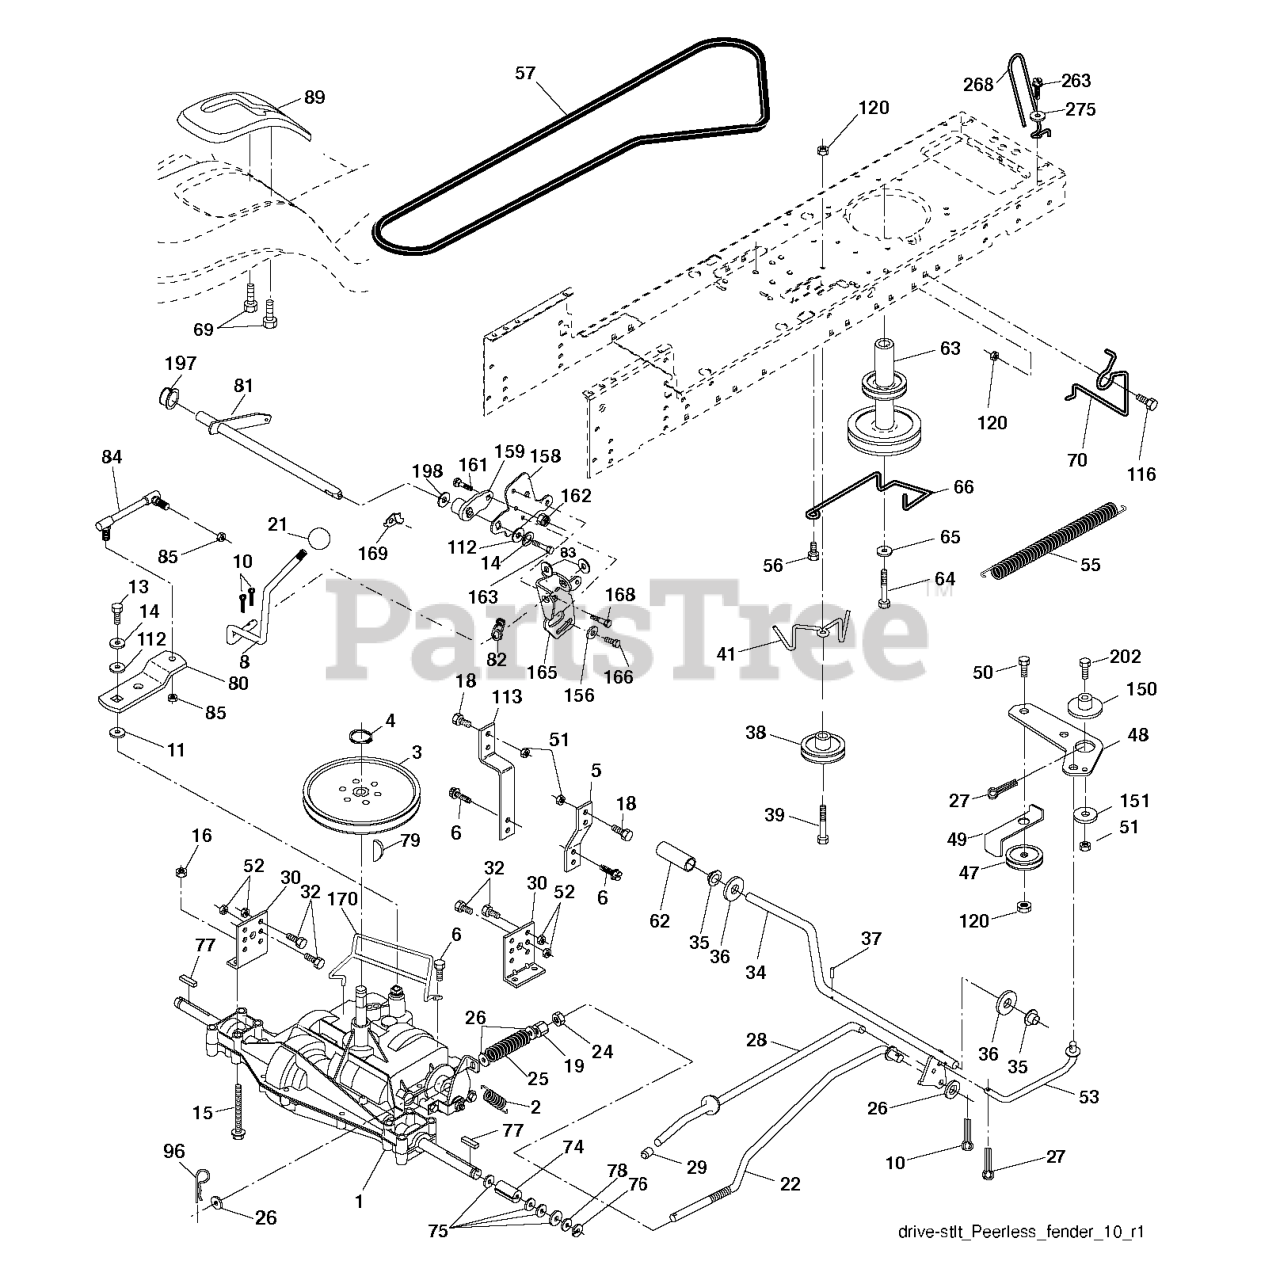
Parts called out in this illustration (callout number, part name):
2	SPRING,BRAKE RETURN
3	PULLEY TRANS
4	RETAINING RING LT
5	STRAP TORQUE
6	SCREW 5/16"
8	ROD SHIFT FENDER ADJUST LT
10	PIN COTTER
11	WASH-SHFT PLT LT
13	BOLT 1/4-28X3/4
14	LOCKWASHER
15	BOLT HEX 5/16-18 GR 5
16	NUT.71038.31-18.HEX.NYLOCK
19	NUT
21	KNOB T (3/8 HOLE)
24	NUT
25	SPRING ROD LT
26	WASHER
27	COTTER PIN
28	ROD, PARKING BRAKE
29	PLUNGER CAP
30	BRKT, MOUNT TRNSAXLE
32	BOLT
34	SHAFT, FOOT PEDAL
35	BEARING.NYLON
37	DRIVE PIN
38	PULLEY IDLER COMPOSITE
41	KEEPER, BELT IDLER
47	IDLER PULLEY
48	BELLCRANK, CLUTCH
49	RETAIN BELT
50	BOLT.3/8-16X1.50
52	LOCKNUT
53	LINK.CLUTCH.7.66.2005
55	SPRING, RETURN LT
56	SCREW.3/8-16
57	BELT, V GROUND DRIVE 95 25
62	PEDAL COVER T
63	ENGINE PULLEY
64	BOLT HEX 7/16-20X4-1/4"
65	LOCKWASHER
66	KEEPER BELT ENGINE
69	SCREW.HI-LO.CONSOLE
70	KEEPER BELT ENG
74	SPACER AXLE
77	SQUARE KEY
79	KEY STD (1373) DANA
81	SHAFT ASM CROSS TAPERED
82	SHIFT SPRING
83	WASHER
84	LINK.TRNSAXLE
85	NUT LOCK CENTER 1/4 -28 FNTHD
89	CONSOLE SHIFT STLT
96	RETAINER M
113	STRAP TORQUE LH LT
116	BOLT D
120	NUT LOCK FLG 3/8-16 UNC
150	SPACER, RETAINER
151	WASHER 12/32X2X10GA
156	WASHER.SRRTD.5/16
158	BRACKET
159	RB HUB.SHIFT
161	BOLT
162	NUT.CROWNLOCK.1/4
165	RP BRACKET
166	CAPSCREW.HXHD.FLG.5/16-18X.625
168	BOLT.SHOULDER.5/16-18X
169	PLATE.FASTENING.CROSS.SHAFT
170	KEEPER BELT T/A
197	NYLINER SNAP 5/8" ID
198	WASHER.NYL.7/8IDX.105"HYD CR
263	SCREW, 3/8-16X3/4
268	GUARD MUFFLER
275	WASHER
